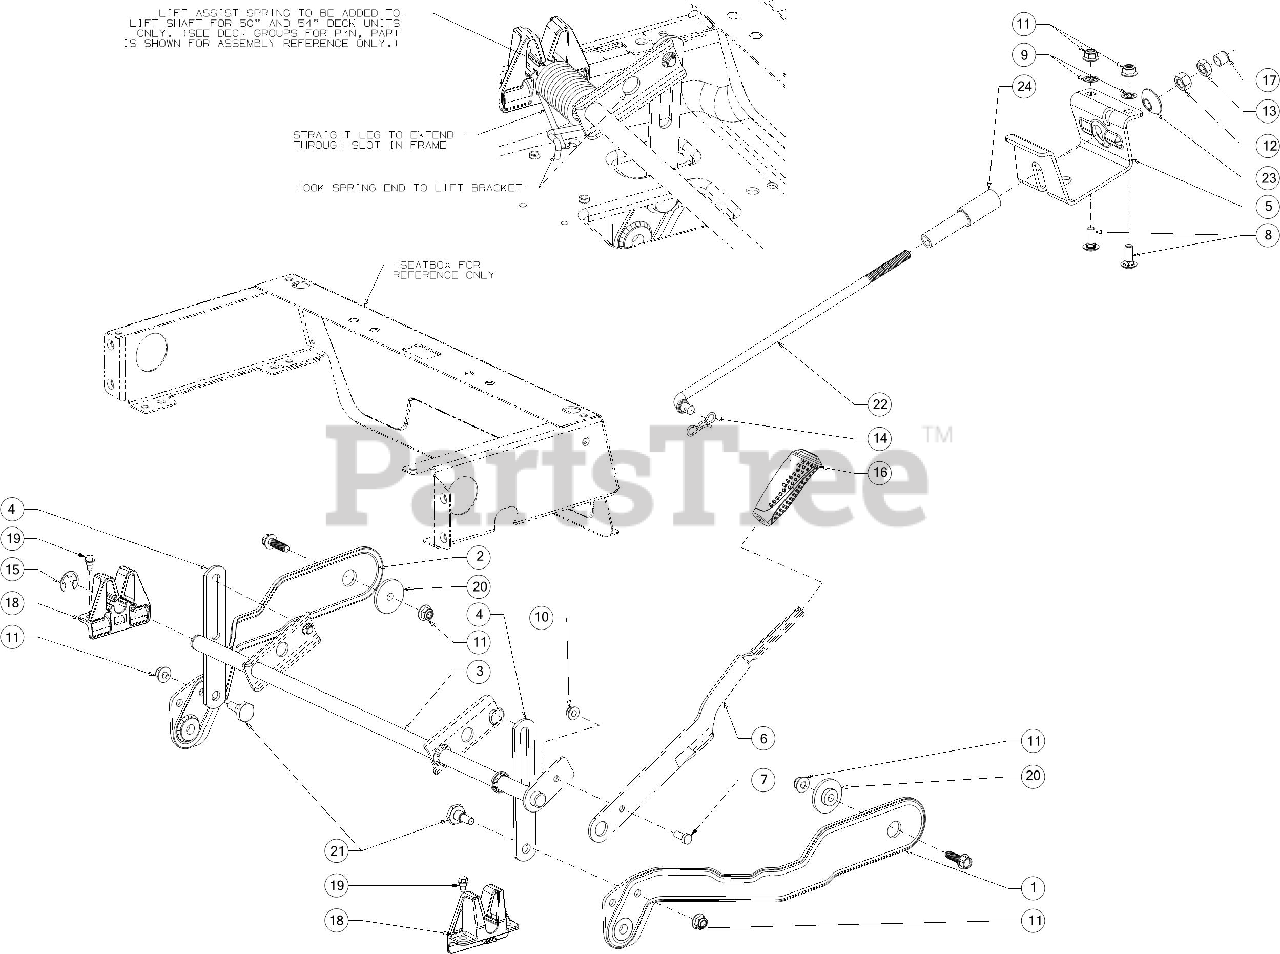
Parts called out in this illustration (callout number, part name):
1	DECK LIFT PLATE ASSEMBLY (RH)
2	DECK LIFT PLATE ASSEMBLY (LH)
3	DECK SHAFT ASSEMBLY
4	LIFT LINK PLATE
5	ROD SUPPORT BRACKET
6	DECK LIFT HANDLE
7	SCREW 5/16-18 x .75 GR5
8	CARRIAGE BOLT 3/8-16 x 1.00 GR5
10	FLANGE LOCK NUT 5/16-18
12	HEX NUT NYLOK 1/2-13
13	HEX NUT
14	BOW TIE COTTER PIN
15	E-RING
17	LIFT ROD END CAP
18	DECK LIFT BRACKET
19	SHOULDER SCREW 1/4-20X.50 19PSH"
20	SHOULDER SPACER -S
21	SHOULDER SCREW
22	DECK FRONT LIFT ROD
23	LIFT PIVOT CUP
24	SLEEVE .55 ID x 4.50 LG
